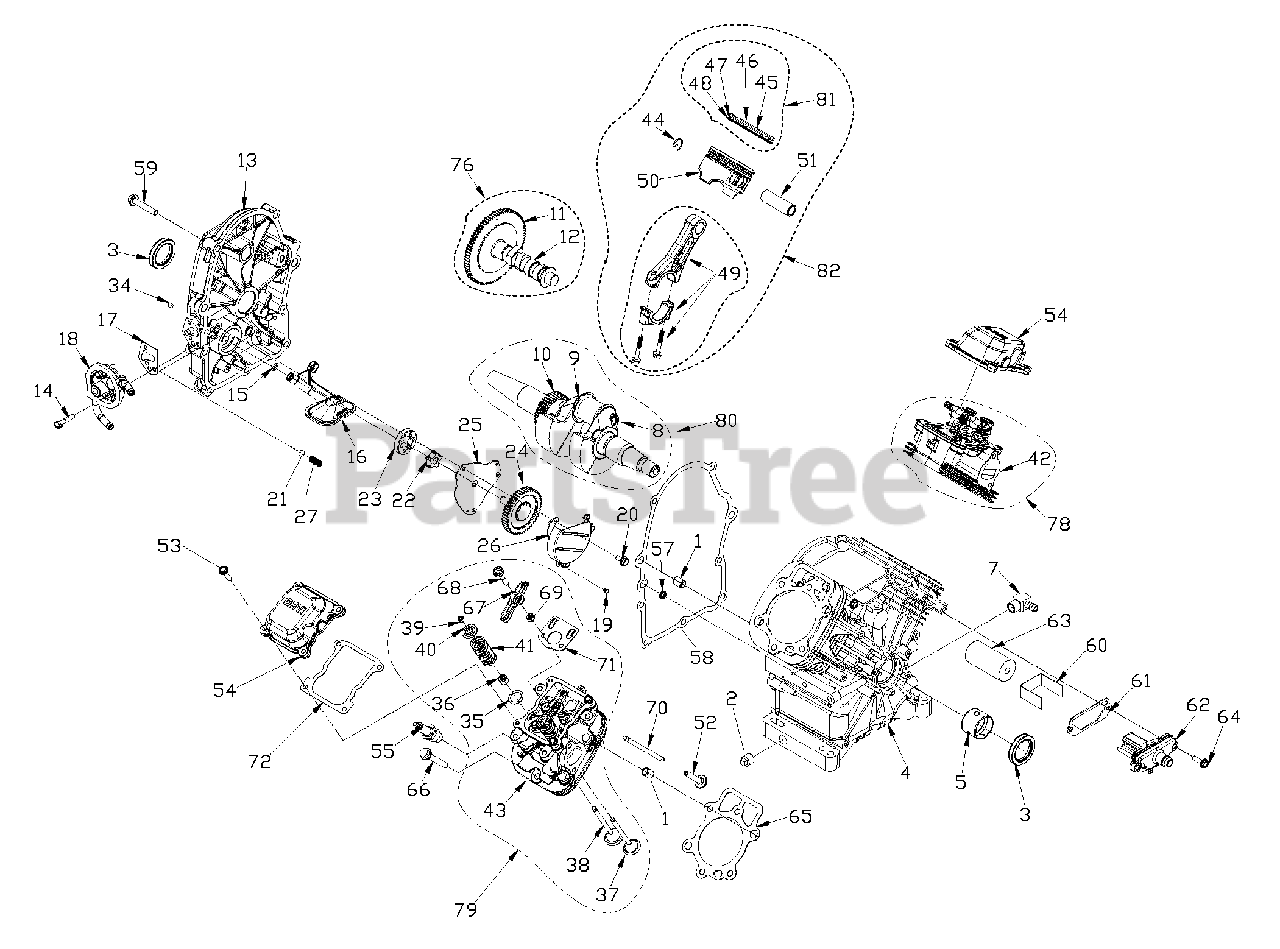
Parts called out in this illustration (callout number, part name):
1	SLEEVE DOWEL PIN 12 DIA
2	PLUG STD PIP 3/8 STEEL
3	SEAL CRANKSHAFT OIL 35 DIA
4	SUBASSEMBLY CRANKCASE GTH530
5	BEARING 35MM GT530
7	ELBOW 90 DEG 3/8 X 3/8 NPT W/VS
8	PLUG EXPANSION
9	CRANKSHAFT GTH530
10	GEAR CRANKSHAFT
11	GEAR CAMSHAFT
12	CAMSHAFT MACHINED W/O CRL
13	GEAR COVER MACHINED
14	SCREW SHC M6-1 X 30 SEMS
15	O-RING 3/8 X 1/2
16	PICKUP SCREEN OIL
17	GASKET OIL FILTER ADAPTOR
18	ASSEMBLY OIL COOLER ADAPTOR W/PRES RELIEF
19	RIVET POP .125 X .275 SS
20	SCREW HHFCS M6-1 X 12
21	BALL RELIEF
22	GEROTOR INNER
23	GEROTOR OUTER
24	GEAR GEROTOR
25	COVER GEROTOR
26	COVER GEAR SHIELD
27	SPRING OIL PRESSURE RELIEF
34	SCREW SHS 5/16/24 X 3/8
35	WASHER VALVE SPRING WEAR
36	SEAL VALVE STEM
37	VALVE EXHAUST
38	VALVE INTAKE
39	KEEPER VALVE SPRING
40	VALVE RETAINER
41	SPRING VALVE SF
42	ASSY CYL HEAD #1 SEATS AND GUIDES
43	ASSY CYL HEAD #2 SEATS AND GUIDES
44	RING RETAINING
45	RING PISTON TOP
46	RING PISTON 2ND
47	RING PISTON OIL RAIL
48	RING PISTON OIL SPACER
49	ASSY CONROD GT530
50	PISTON COATED
51	PIN PISTON
52	TAPPET
53	SCREW HHFC M6-1.0 X 8
54	COVER ROCKER GT530
55	SPARKPLUG
57	SEAL OIL PASSAGE
58	GASKET CRANKCASE
59	SCREW HHFC M8-1.25 X 45
60	SEPARATOR OIL GT530 BREATHER
61	GASKET BREATHER
62	ASSY BREATHER
63	SEPARATOR OIL BREATHER
64	SCREW HHFC M6-1.0 X 20
65	GASKET CYLINDER HEAD
66	SCREW HHC M8-1.25 X 56
67	ARM ROCKER
68	STUD ROCKER ARM PIVOT
69	NUT JAM M6-0.75 FINE THREAD
70	PUSHROD
71	PLATE PUSHROD GUIDE
72	GASKET VALVE COVER
76	ASSY CAM AND GEAR
77	RING RETAINING E-STYLE
78	KIT HEAD ASSY CYL #1
79	KIT HEAD ASSY CYL #2
80	ASSY CSHAFT W/PLUG
81	RING SET DIA 75
82	ASSY PISTON AND CONNECTING ROD
